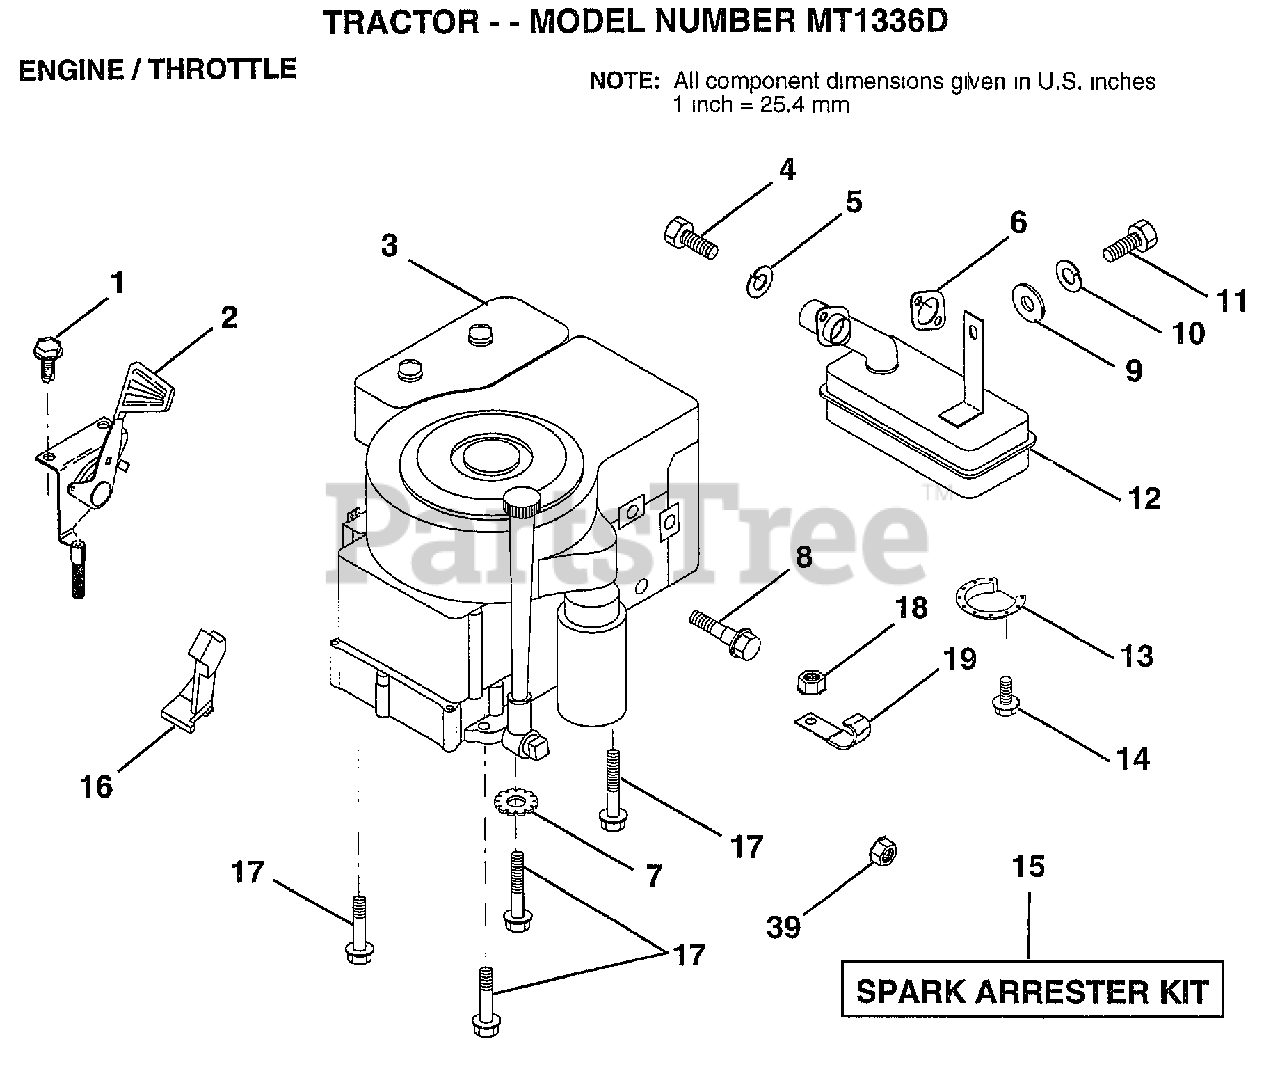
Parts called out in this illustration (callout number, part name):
1	SCREW LT
4	SCREW
5	LOCKWASHER
7	LOCKWASHER
8	BOLT T
10	LOCKWASHER
12	MUFFLER
13	DEFLECTOR.222573
16	"STOP,DASH THROTT"
17	SCREW LT
18	NUT
19	CLIP T
39	NUT
